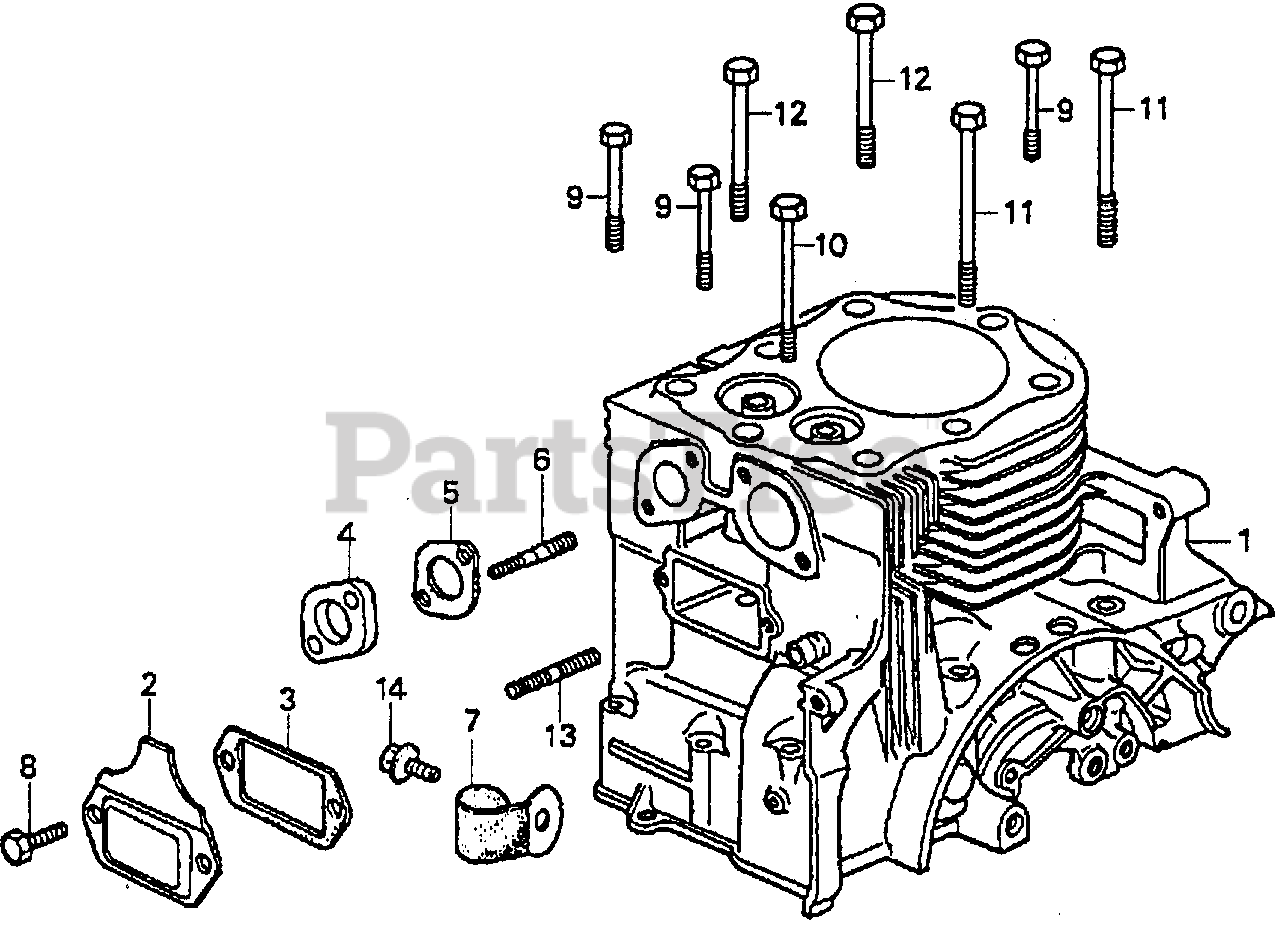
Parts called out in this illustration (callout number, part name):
2	COVER, TAPPET (NOT AVAILABLE)
3	GASKET, TAPPET
4	INSULATOR, CARBURETOR
5	GASKET, CARBURETOR INSULATOR (NOT AVAILABLE)
6	BOLT, STUD (8X39)
7	CLAMP, CORD (NOT AVAILABLE)
8	BOLT, HEX. (6X12)
9	BOLT, HEX. (6X63)
10	BOLT, HEX. (6X90)
11	BOLT, HEX. (8X100)
12	BOLT, HEX. (8X80) (SOURCE: VINTAGE PARTS INC.)
13	BOLT, STUD (6X32)
14	BOLT-WASHER (8X12)
